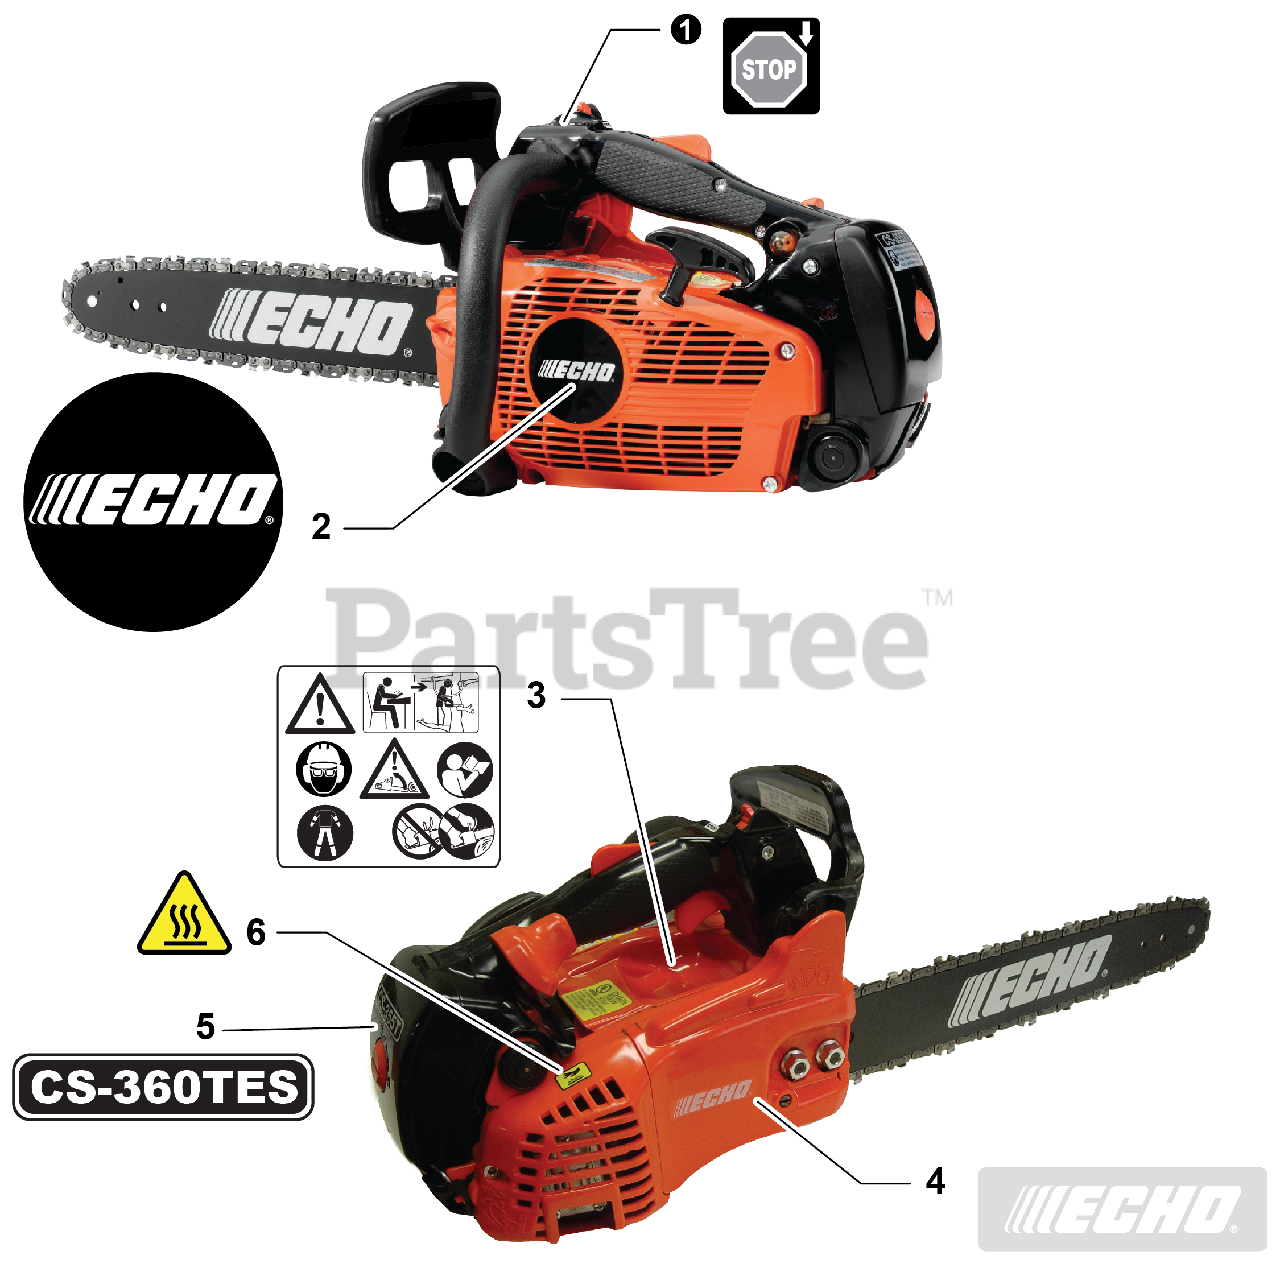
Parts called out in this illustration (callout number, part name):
1	LABEL, ON-OFF
2	LABEL, ECHO
3	LABEL, CAUTION
4	LABEL, ECHO
5	LABEL, MODEL
6	LABEL, CAUTION - HOT
